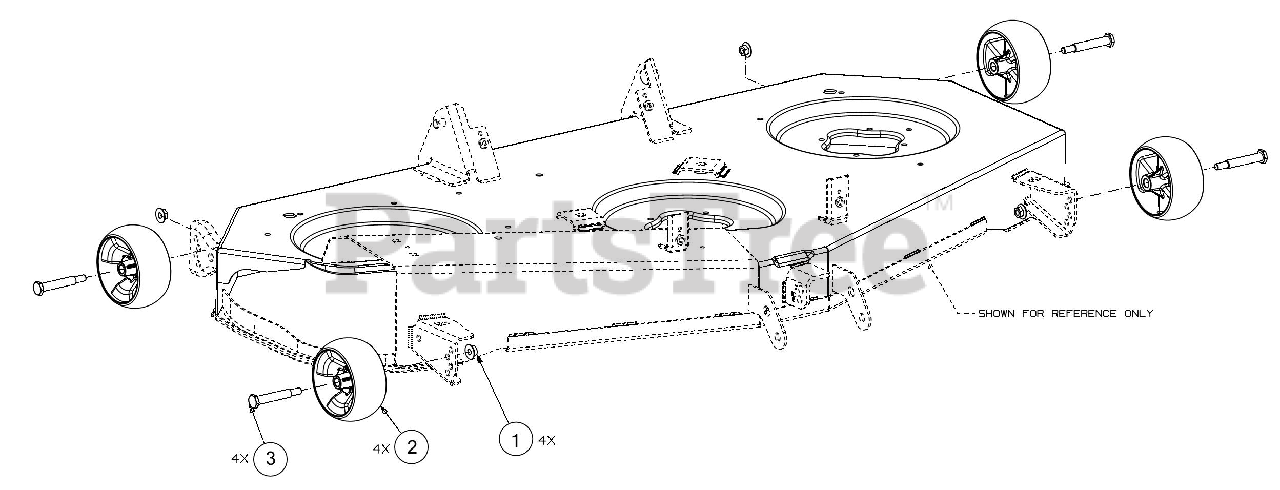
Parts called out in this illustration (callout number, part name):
1	FLANGE LOCK NUT
2	DECK WHEEL
3	SHOULDER BOLT
